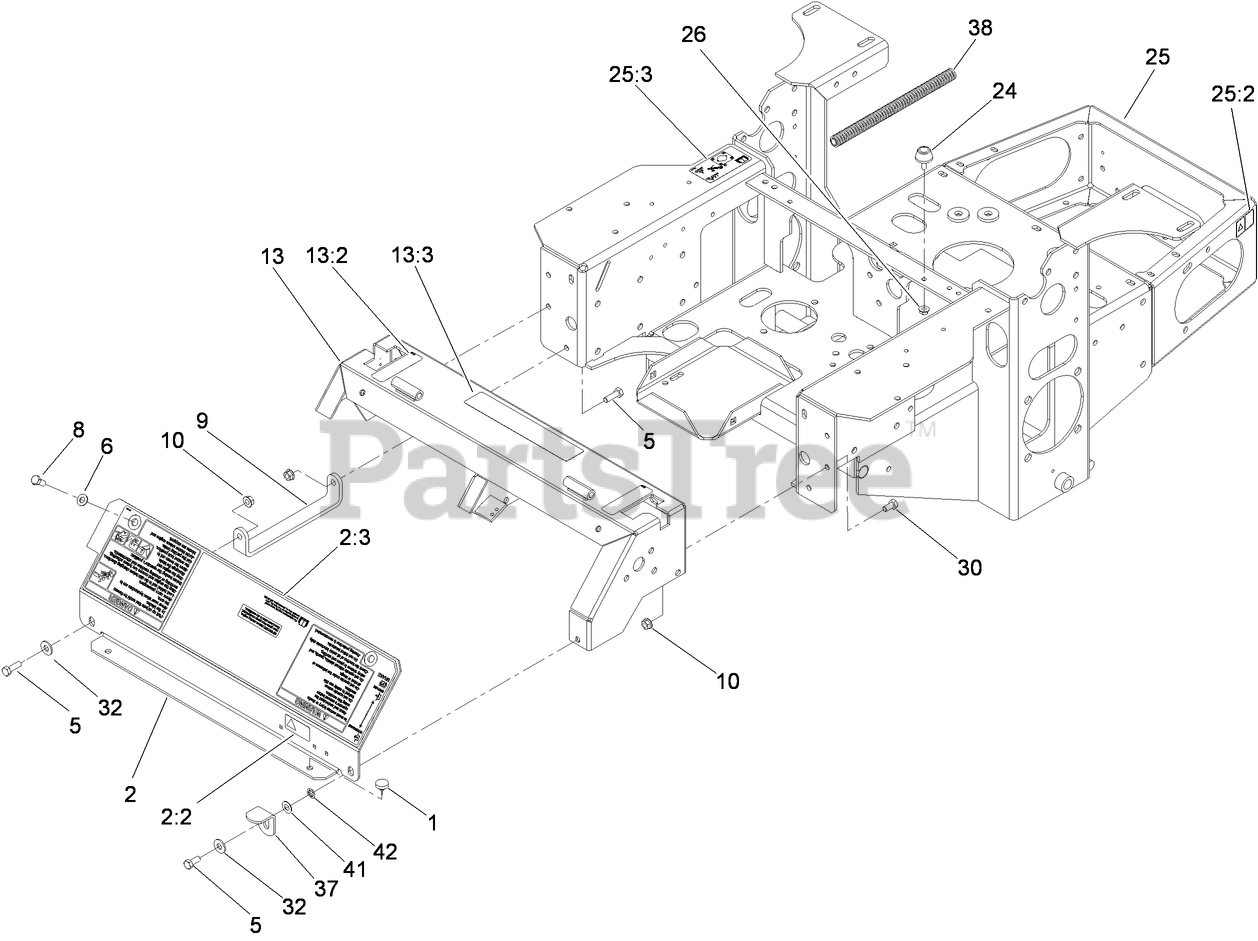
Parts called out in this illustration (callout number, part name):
1	BUMPER
2	PANEL ASM
2:2	DECAL-PROTECTION, EAR
2:3	DECAL-PANEL, FRONT
5	SCREW-HH
6	WASHER-PLAIN
8	SCREW-HH
9	BRACKET-PANEL, INSTRUMENT
10	NUT-HF
13	CONSOLE
13:2	DECAL-CONTROL, MOTION
13:3	DECAL-BATTERY
24	BUMPER-RUBBER
25	MAIN FRAME ASM
25:2	DECAL-WARNING
25:3	Decal-Release, Drive
26	NUT-HF
30	SCREW-HH
32	WASHER-FLAT
37	STOP-COVER
38	CONDUIT-CONVOLUTED, SPLIT
41	WASHER-THRUST
42	NUT-PUSH
